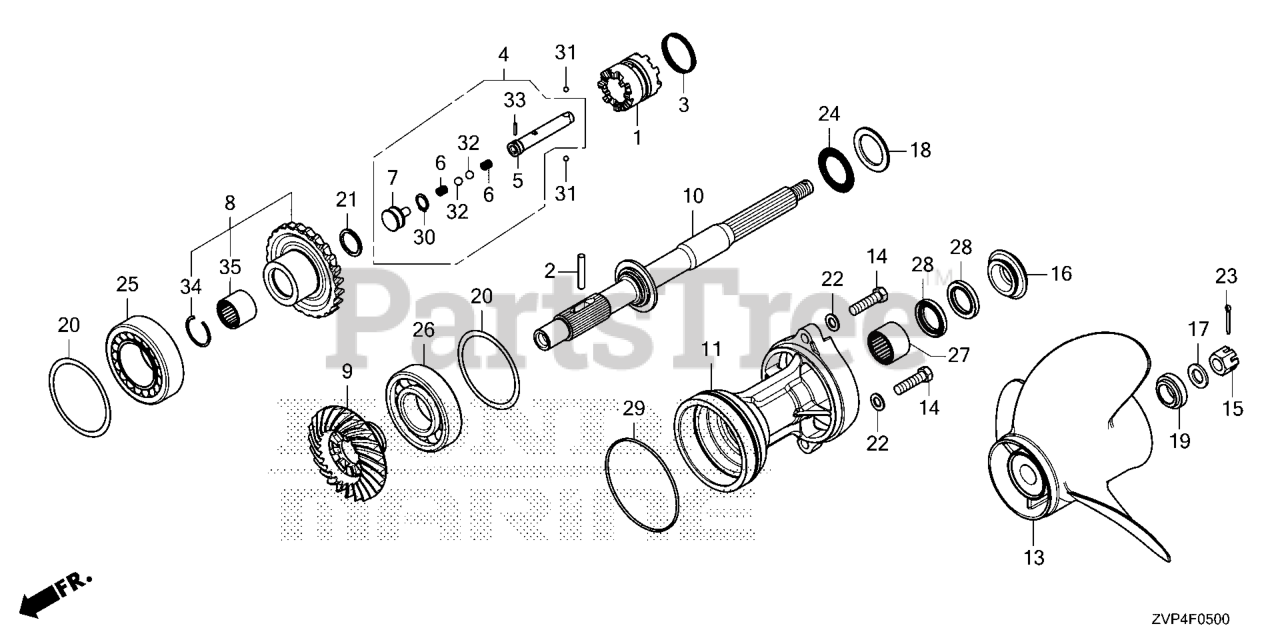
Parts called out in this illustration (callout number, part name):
1	SHIFTER, CLUTCH
2	PIN, SHIFTER (8X50)
3	RING, CROSS PIN
4	SLIDER COMP, SHIFT
5	SLIDER, SHIFT
6	SPRING, SHIFT
7	PLATE, SHIFT
8	GEAR COMP, BEVEL F
9	GEAR, BEVEL R
10	SHAFT, PROPELLER
11	HOLDER *NH565*
11	HOLDER *NHB14M*
13	PROP COMP (3-BLADE)
14	BOLT, HEX. (12X45)
15	NUT, CASTLE (18MM)
16	WASHER, PROP THRUST
17	WASHER, PLAIN (18.5MM)
18	WASHER, THRUST BEARING
19	WASHER, PROP
20	SHIM A, BEVEL F
20	SHIM B, BEVEL F
20	SHIM C, BEVEL F
20	SHIM D, BEVEL F
21	SHIM C, THRUST (2.85)
21	SHIM D, THRUST (2.90)
21	SHIM E, THRUST (2.95)
21	SHIM F, THRUST (3.00)
21	SHIM G, THRUST (3.05)
21	SHIM H, THRUST (3.10)
22	WASHER, PLAIN (12MM)
23	PIN, SPLIT (4.0)
24	BEARING, THRUST (F)
25	BRG (60X110X38)
26	BRG (50X110X27)
27	BRG (35X45X30)
28	SEAL (35X50X7)
29	O-RING (121X3.1)
30	CIRCLIP (OUTER) (18MM)
31	BALL, STEEL (#7) (7/32)
32	BALL, STEEL (#12) (3/8)
33	ROLLER (3X16.8)
34	RING, SETTING (39)
35	BEARING, NEEDLE (28X39X30)
